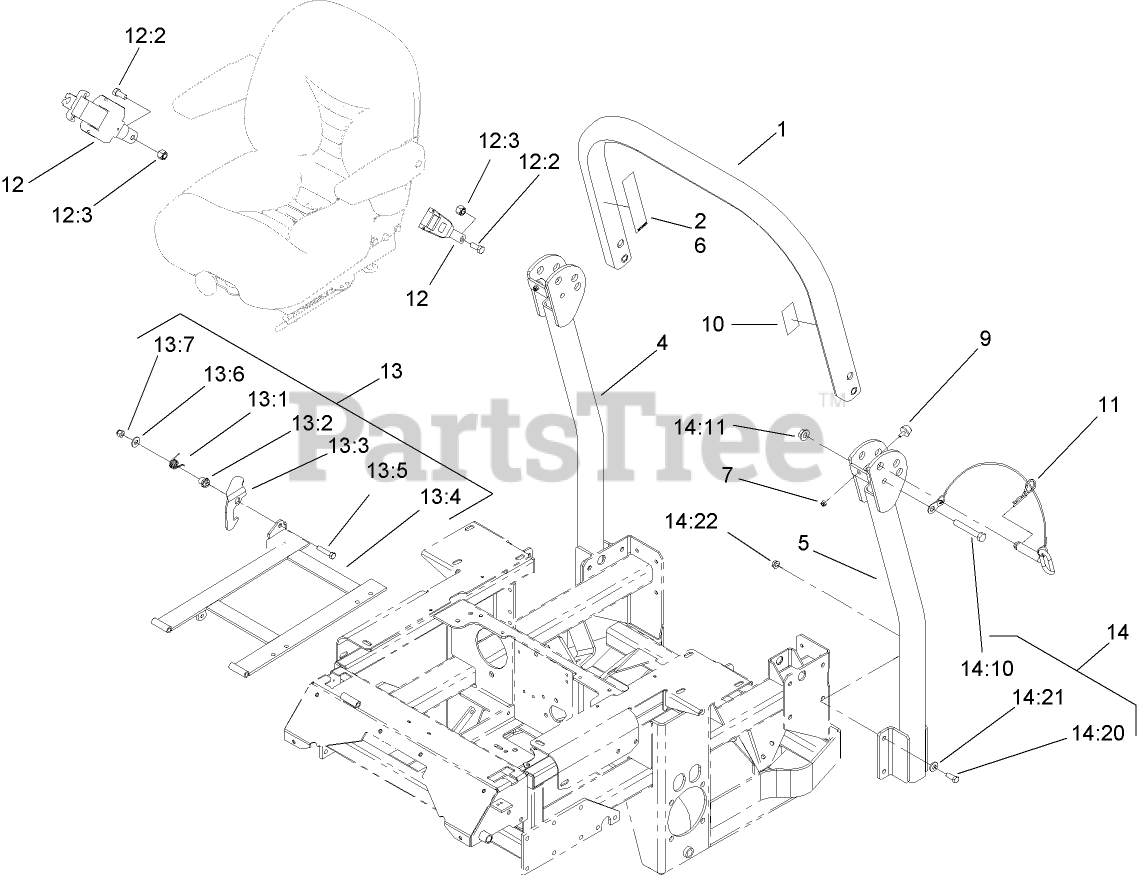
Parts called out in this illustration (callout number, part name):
1	Upper Tube ASM
2	DECAL-WARNING, FOLDING ROPS
4	TUBE-SUPPORT, RH
5	TUBE-SUPPORT, LH
6	DECAL-WARNING
7	NUT-LOCK, NI
9	BUMPER-RUBBER
10	DECAL-ROPS
11	PIN-FOLD, ROPS
12	RETRACTABLE SEATBELT KIT
12:2	SCREW-HH
12:3	NUT-LOCK
13	SEAT FRAME SINGLE LATCH ASM
13:1	CATCH-LATCH, SINGLE
13:2	SPRING-TORSION, LATCH
13:3	BUSHING-LATCH, SEAT
13:4	FRAME-SEAT, SINGLE LATCH
13:5	WASHER-FLAT
13:6	NUT-LOCK, NI
13:7	SCREW-HH
14	BAG-BOLT
14:10	SCREW-HH
14:11	NUT-HF
14:20	SCREW-HH
14:21	WASHER-BELLEVILLE
14:22	NUT-HHF, WHIZ
